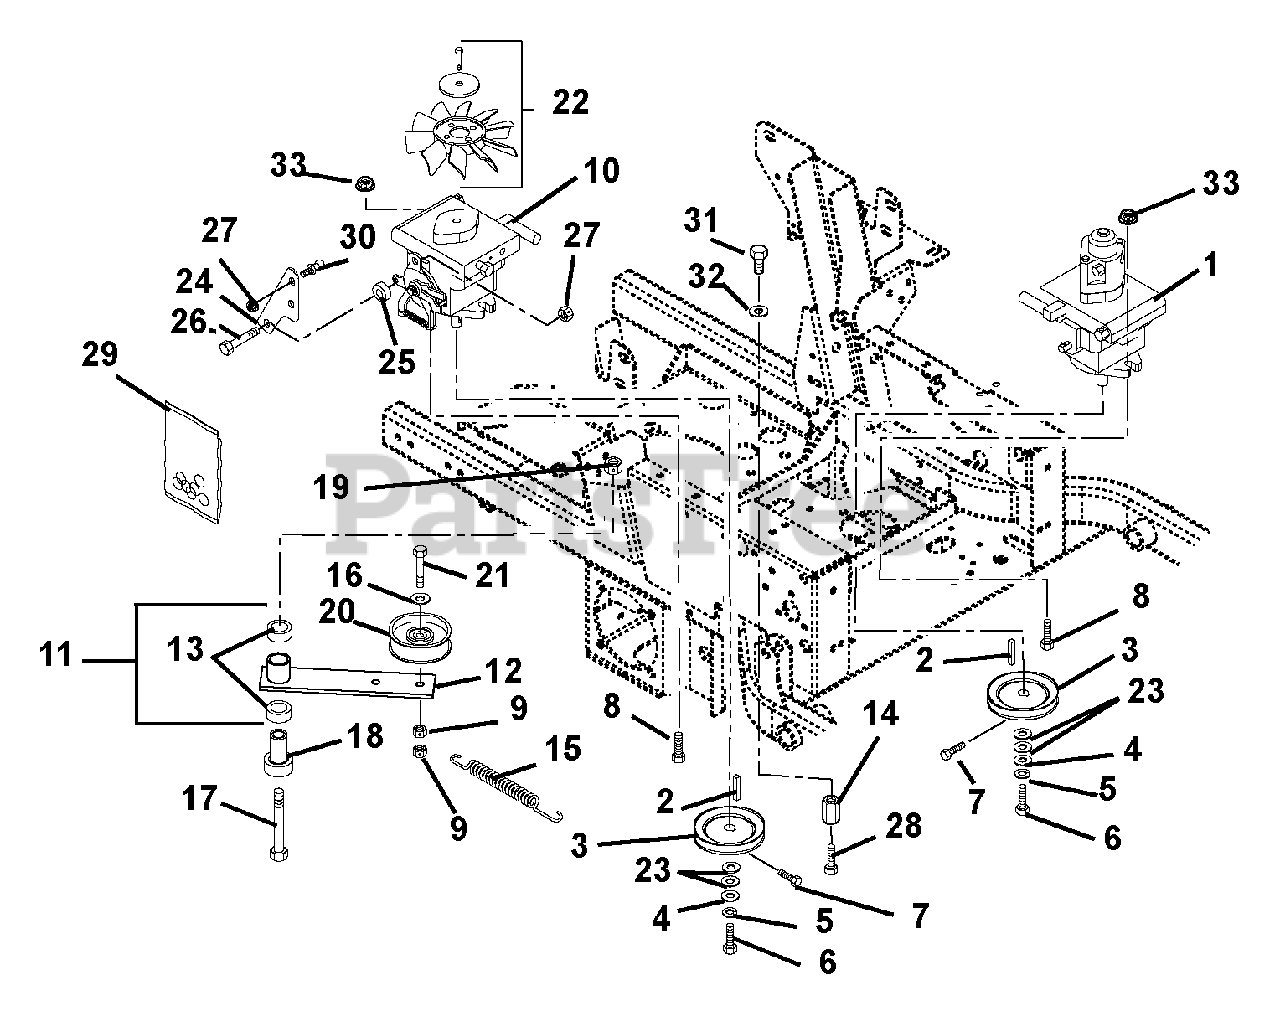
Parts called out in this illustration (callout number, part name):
1	Hydrostat BDP with Auxiliary
2	Key, Straight 5mm x 25mm x 5mm
3	Sheave 4.0 x .199
4	Washer, Flat Steel .281 x 1.00 x .063
5	Washer, Locking .25 x .062
6	Bolt, Hex M6 x 1.0 x 12
7	Bolt, Hex .25-20 x .50 Grade 5
8	Bolt-Round Head Square Neck .44-14 x 1.50 Grade 5
9	Nut, Locking Top Flange .38-16
11	Assembly, Idler Arm Guard Drive
12	Weldment, Idler Arm Ground Drive
13	Bearing, 1.00 x 1.12 x .75
14	Nut Coupling .375-16 x 1.75
15	Spring, Tension .120 x .845 x 6.50
16	Washer, Flat Steel .39 x.75 x.125
17	Bolt, Hex .50-13 x 3.50 Grade 5
18	Bearing, Pedestal Powdered Metal
19	Nut, Locking Top Flange .50-13
20	Idler, Flat 4.00 x 1.06
21	Bolt, Hex .38-16 x 2.25 Grade 5
22	Fan, Cooling
23	Washer, Flat Steel .656 x 1.31 x .095
24	Bracket, Return to Neutral/Damper
25	Spacer .344 x 1.00 x .375
26	Bolt, Hex .31-18 x 1.25 Grade 5
27	Nut, Locking Top Flange .31-18
28	Bolt-Hex .38-16 x 1.50 Grade 5
29	Kit, Pump Seal (BDP-10A)
30	Stud, Ball
31	Bolt-Hex .38-16 x .75 Grade 5
32	Washer, Locking .38 x .094
33	Nut-Nyloc Flange .44-14
